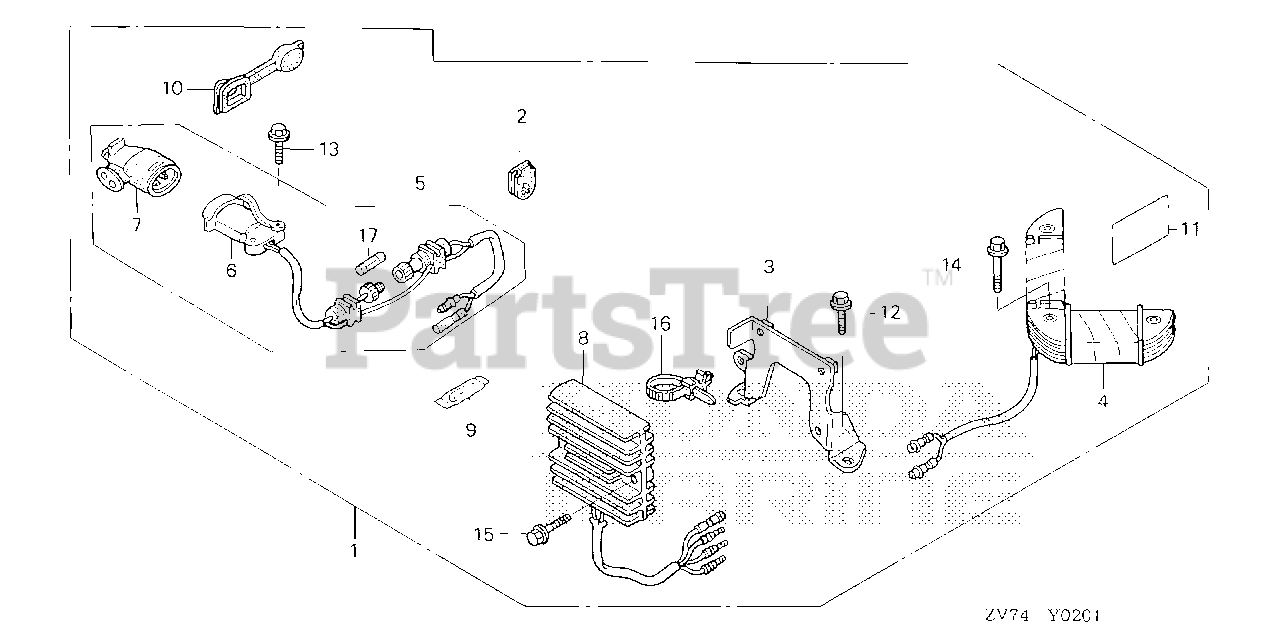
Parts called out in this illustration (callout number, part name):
1	RECEPTACLE KIT, CHARGE (10A)
2	GROMMET, WIRE
3	BRACKET, REGULATOR
4	COIL ASSY., CHARGE (12V-10A)
5	RECEPTACLE ASSY., CHARGE
6	RECEPTACLE
7	PLUG, RECEPTACLE
8	RECTIFIER ASSY., REGULATOR
9	FUSE, SPARE (15A)
10	GROMMET, CASE (LOWER) (C)
11	MARK, RECEPTACLE (10A)
12	BOLT, FLANGE (6X12) (CT200)
13	BOLT, FLANGE (5X22)
14	BOLT, FLANGE (6X35) (CT200)
15	BOLT, FLANGE (6X20)
16	STRAP, CABLE (118MM) (BLACK)
17	FUSE (15A)
